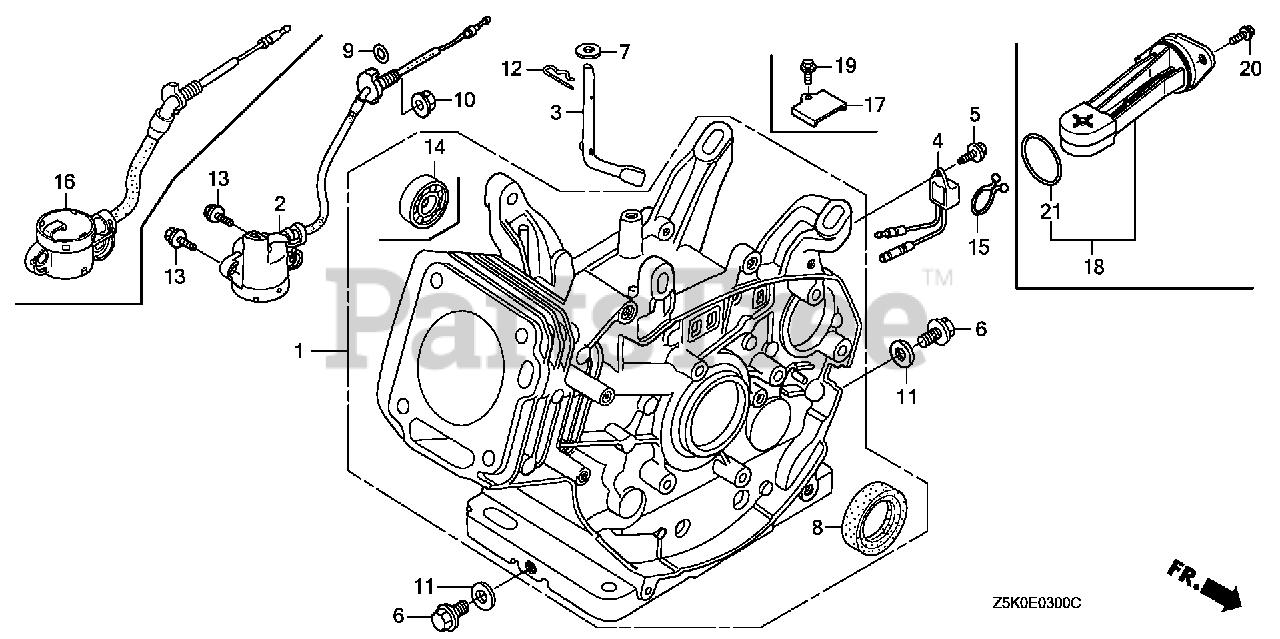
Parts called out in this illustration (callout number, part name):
1	CYLINDER ASSY.
6	BOLT, DRAIN PLUG
8	OIL SEAL (30X46X8) (NOK ASIA)
11	WASHER, DRAIN PLUG (12MM)
14	BEARING, RADIAL BALL (6202)
17	BRACKET A, HARNESS
18	SWITCH ASSY., OIL LEVEL
19	BOLT, FLANGE (6X12) (CT200)
20	BOLT, FLANGE (6X16)
21	O-RING (37.9X2.4)
